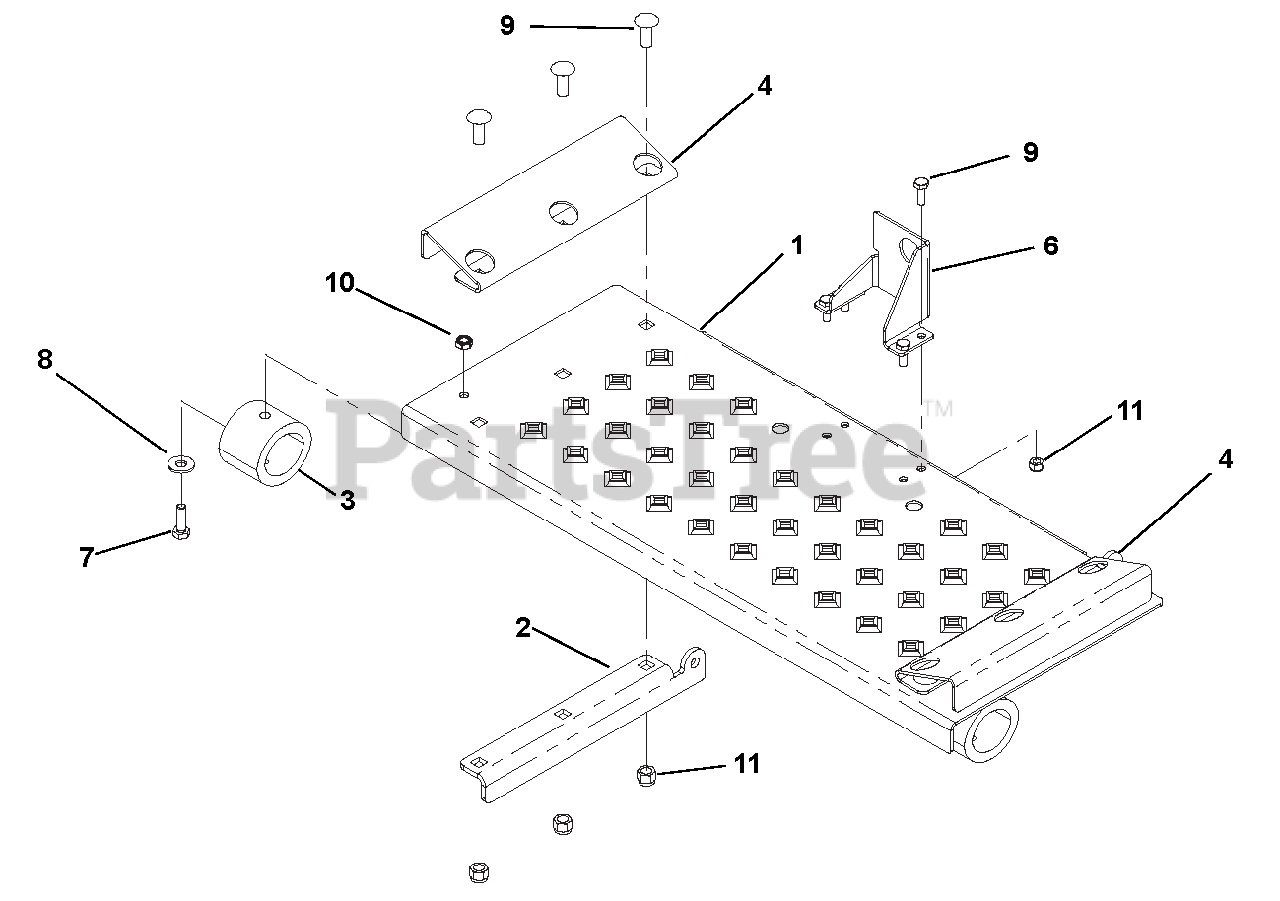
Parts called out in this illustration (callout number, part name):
1	PLATE, PLATFORM
2	PLATE, PLATFORM TAB
3	CLUTCH ASSY, OGURA
4	WEDGE, PLATFORM
5	PLATE, PLATFORM TAB LH
6	COVER, OPC
7	@BLT-HEX .31-18X1.00 GR5 YWZC
8	@WSHR-FL-STL.38X.875X.083 YWZC
9	@BLT-RDHDSHSQNK.38-16X1.0 G5YZ
10	@NUT-LK-NYL .312-18 YWZC
11	@NUT-LK-NYL .38-16 YWZC
